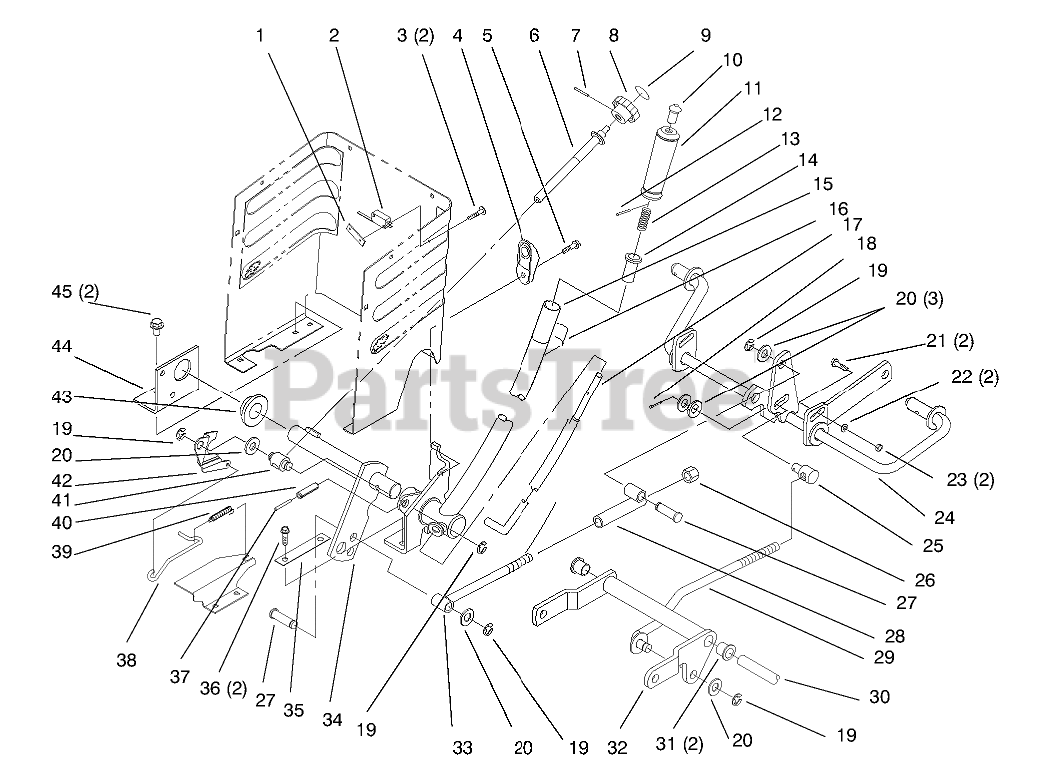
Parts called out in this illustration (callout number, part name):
1	NUT-SPEED
2	SWITCH-MICRO
3	SCREW-PPHTF
4	WEDGE - HOC
5	SCREW-HWH
6	ROD - HOC
7	PIN-SPIROL
9	DECAL-HEIGHT KNOB
10	TIP-ROD
11	GRIP-HANDLE
12	PIN-SPIROL
13	SPRING-COMPRESSION
14	RETAINER-SPRING
15	LEVER-LIFT
16	Decal-Lift (Only On: 72046)
16	Decal-Lift (Only On: 72064)
17	ROD-LEVER, LIFT
18	PIN-COTTER
19	RING-RETAINING, EXTERNAL
20	WASHER-FLAT
21	BOLT-CARR
22	WASHER-FLAT
23	NUT-LOCK, NI
24	SHAFT-GAGE
25	ROD-TRUNNION LIFT
26	NUT-LOCK, NI
30	SHAFT-PIVOT, PEDAL
31	BUSHING-FLANGE
32	ARM-PIVOT
34	SHAFT-LIFT
36	SCREW-HWHTF
37	PIN-SPRING
38	ROD - HOC INDICATOR
39	SPRING - EXTENSION
40	PIN-ROLL
41	TRUNNION
42	PLATE - HOC GAGE
43	BEARING-FLANGE
44	BRACKET-PIVOT, LINKAGE
45	SCREW-HWHTF
